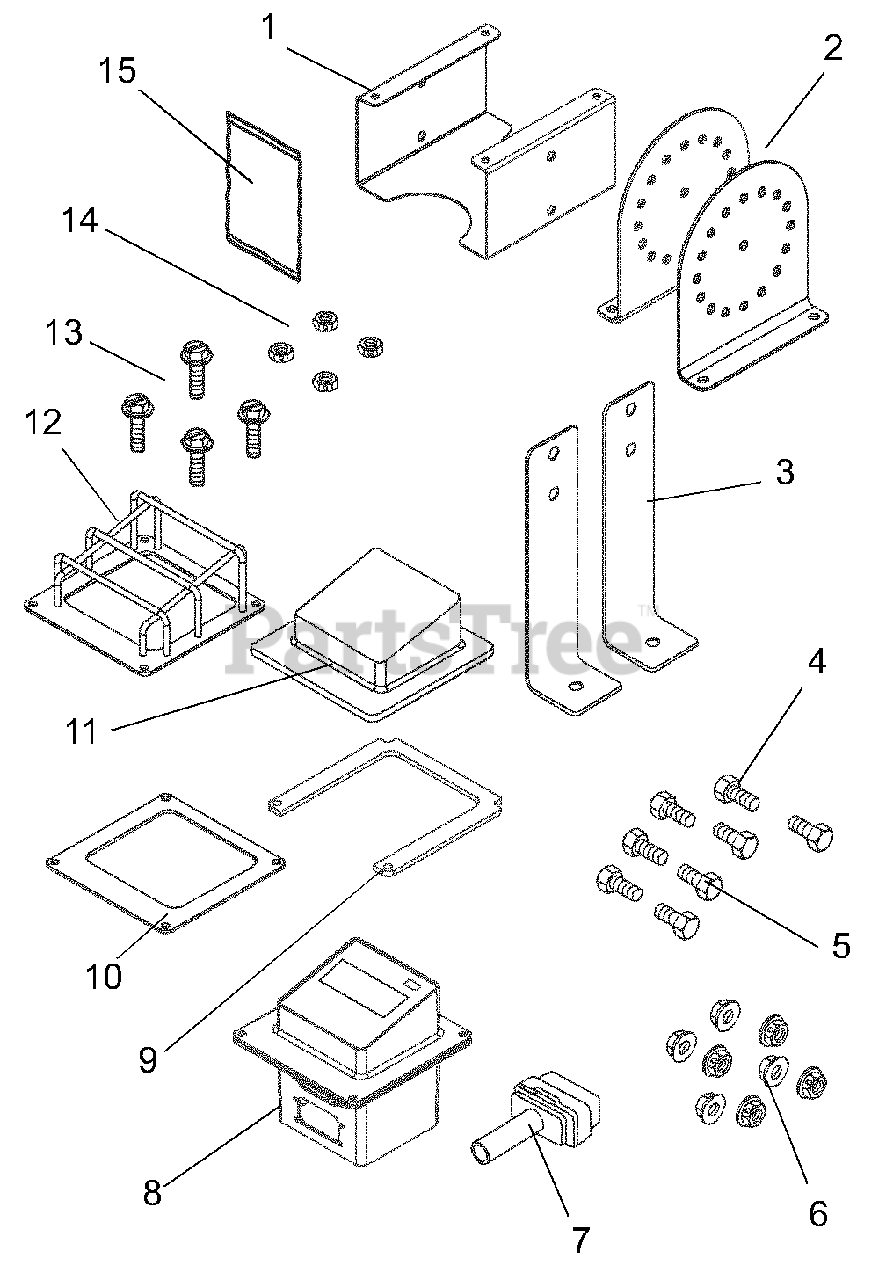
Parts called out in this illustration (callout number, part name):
1	BRKT, EYE-Q RETRO FIT
2	LEG, EYE-Q RETRO FIT
3	LEG, LONG EYE-Q
4	@BLT-HEX .25-20X1.00 GR5 YWZC
5	@BLT-HEX .25-20X.50 GR5 YWZC
6	@NUT-LK-TOP-FLG .25-20 YWZC
7	HARNESS,EYE-Q RETRO FIT CONN.
8	ASSY, EYE-Q
9	SPACER, ENCLOSURE MTG. (BTM)
10	GASKET-EYE Q
11	GUARD, ELEMENT
12	GUARD, VINYL EYE-Q
13	@SCR-MCH 10-24X1.50 HWH YWZC
14	@NUT-LK-NYL 10-24 W/INSRT YWZC
15	MANUAL, EYE-Q USER
